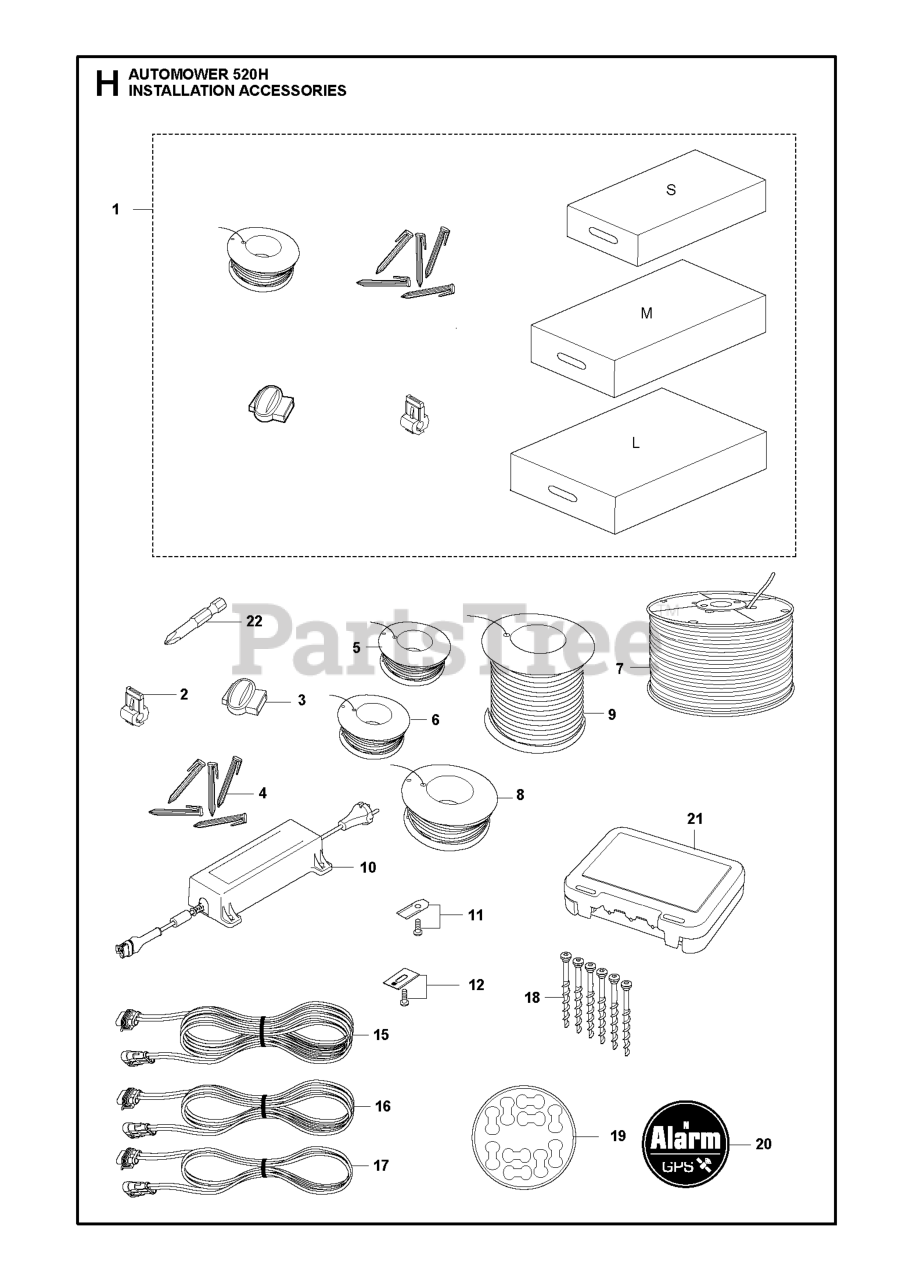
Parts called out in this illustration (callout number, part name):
1	MED AUTOMOWER INSTALL KIT
1	SMALL AUTOMOWER INSTALL KIT
1	LARGE AUTOMOWER INSTALL KIT
2	BRAKER
2	CONNECTOR 100 PCS
2	CONNECTOR 5 PCS, BLISTER
3	COUPLER SPLICER, 100 PCS
3	COUPLER SPLICER, 5 PCS,
3	SPLICE KIT
4	STAPLE 100 PCS, BLISTER
4	STAPLE 100 PCS
5	WIRE 50M STANDARD Ø2.7MM,BLIST
5	WIRE BOUNDARY 150M
5	WIRE 150M, BLISTER
6	WIRE 250M
8	WIRE 500M
9	WIRE (800M)
10	POWER UNIT 2.2A USA/CA
11	HUS BLADE SET 9 PCS
11	HUS BLADE SET 45 PCS
11	HUS BLADE SET 300 PCS
15	CABLE LOW VOLTAGE CABLE P2 5-7
16	CABLE LOW VOLTAGE CABLE P2 5-7
17	CABLE LOW VOLTAGE CABLE P2 5-7
18	Screws
18	SCREW 3 PCS, BLISTER PACK
19	STICKER CABLE MARKERS KIT 10PC
20	Decals
21	CONNECTOR PROTECTION BOX
22	WRENCH BITS CHANGING ROBOTIC B
